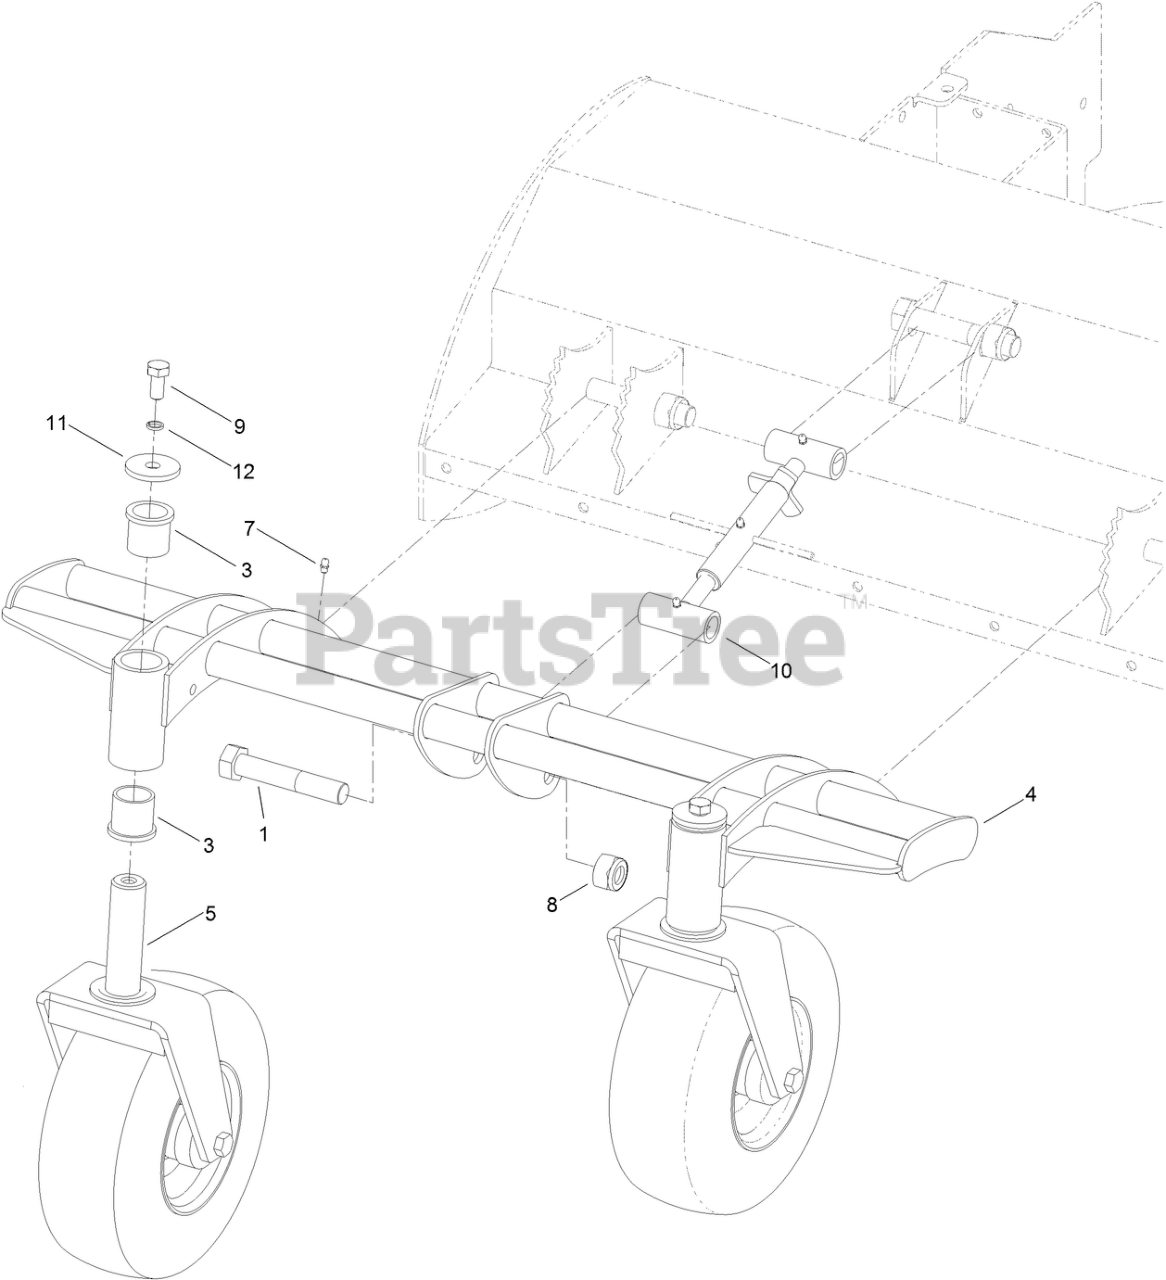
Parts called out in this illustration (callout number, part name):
3	BUSHING-CASTER WHEEL
4	CARRIER-CASTER
5	FORK-CASTER
7	FITTING-GREASE
8	NUT-NYLOC
9	SCREW-HH
10	TURN BUCKLE ASM
11	WASHER
12	WASHER-LOCK
